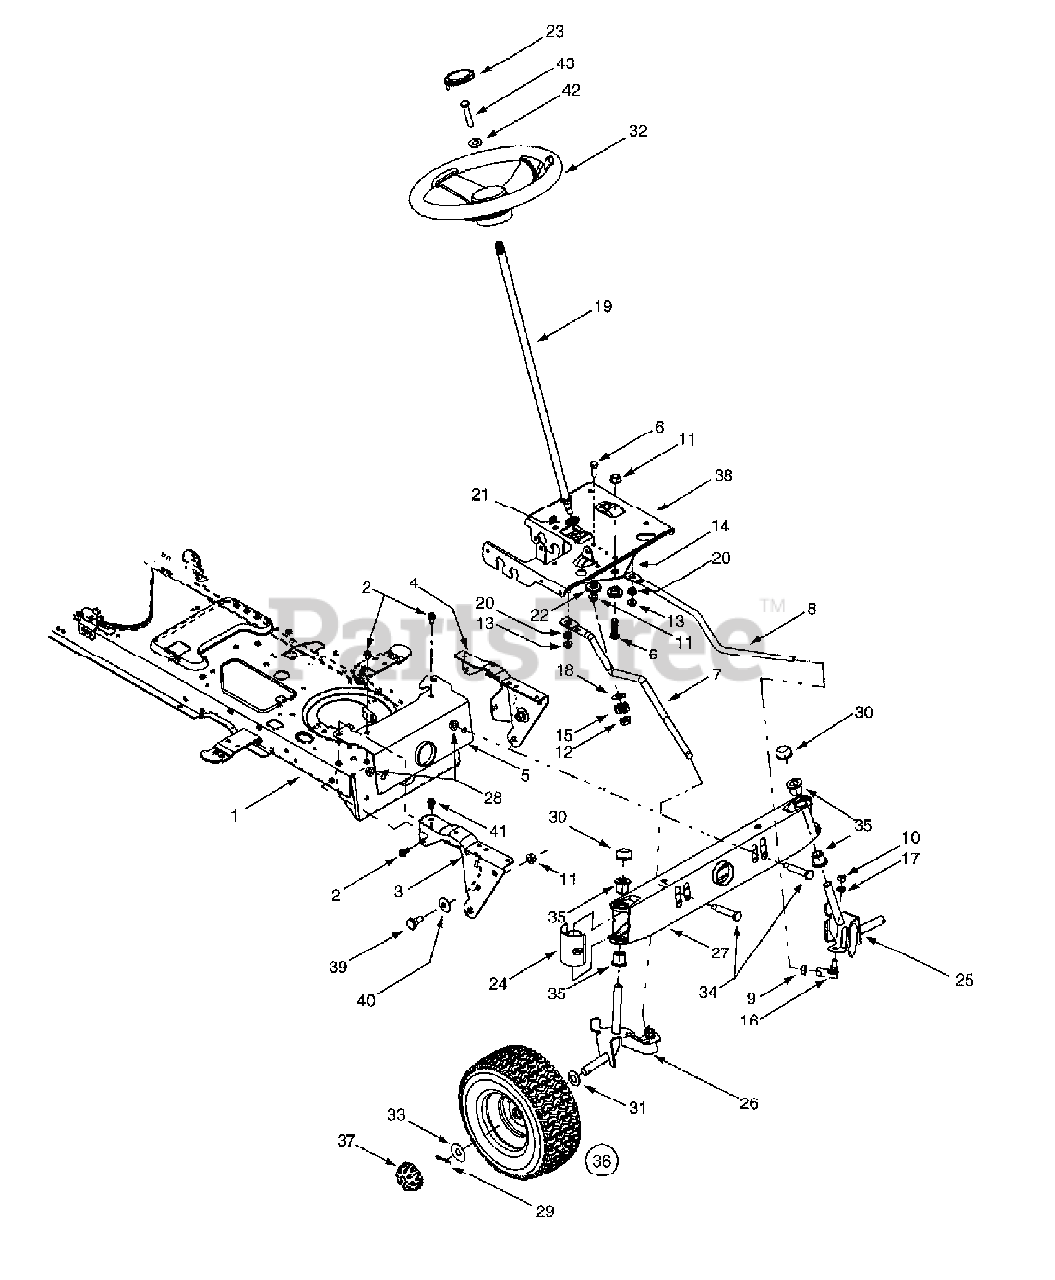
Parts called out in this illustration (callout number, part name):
6	Hex Cap Screw, 3/8-16 x 1.25 (Grade 5)
7	RH Drag Link
8	LH Drag Link
9	Jam Nut, 7/16-20 (Grade 2)
10	Hex Nut, 3/8-24 (Grade 2)
11	Flange Lock Nut, 3/8-16
12	Flange Lock Nut, 7/16-20
13	Flange Lock Nut, 5/16-18
14	Steering Gear, 11/90 Ratio
15	Steering Pinion Gear
16	Ball Joint, 7/16-20
17	Lock Washer, 3/8
18	Flat Washer, .51 x 1.12 x .06
19	Steering Shaft, .625 OD x 24.4
20	Plastic Bushing, .38 ID
21	Hex Flange Bearing, 5/8
22	Shoulder Spacer, .38 ID
23	Steering Wheel Cap, Round
24	Pivot Bar End Cap w/ Fitting
25	LH Axle Assembly, .75 Diameter
26	RH Axle Assembly, .75 Diameter
28	Flange Lock Nut, 3/8-16
29	Cotter Pin
30	Push Cap, .75
31	Flat Washer, .78 x 1.589 x .06
32	Steering Wheel, Soft Grip, Three Spoke
33	Flat Washer, .635 x 1.589 x .06
34	Shoulder Screw, .5 x 2.2, 3/8-16
35	Flange Bearing, .76 ID x .937 OD
37	Deluxe Hub Cap
39	Shoulder Screw, 3/8-16
40	Bell Washer, .39 x 1.13 x .062
41	Self-tapping Screw, 5/16-18 x .75
42	Bell Washer, .34 x .872
43	Hex Bolt, 5/16-18 X 1
